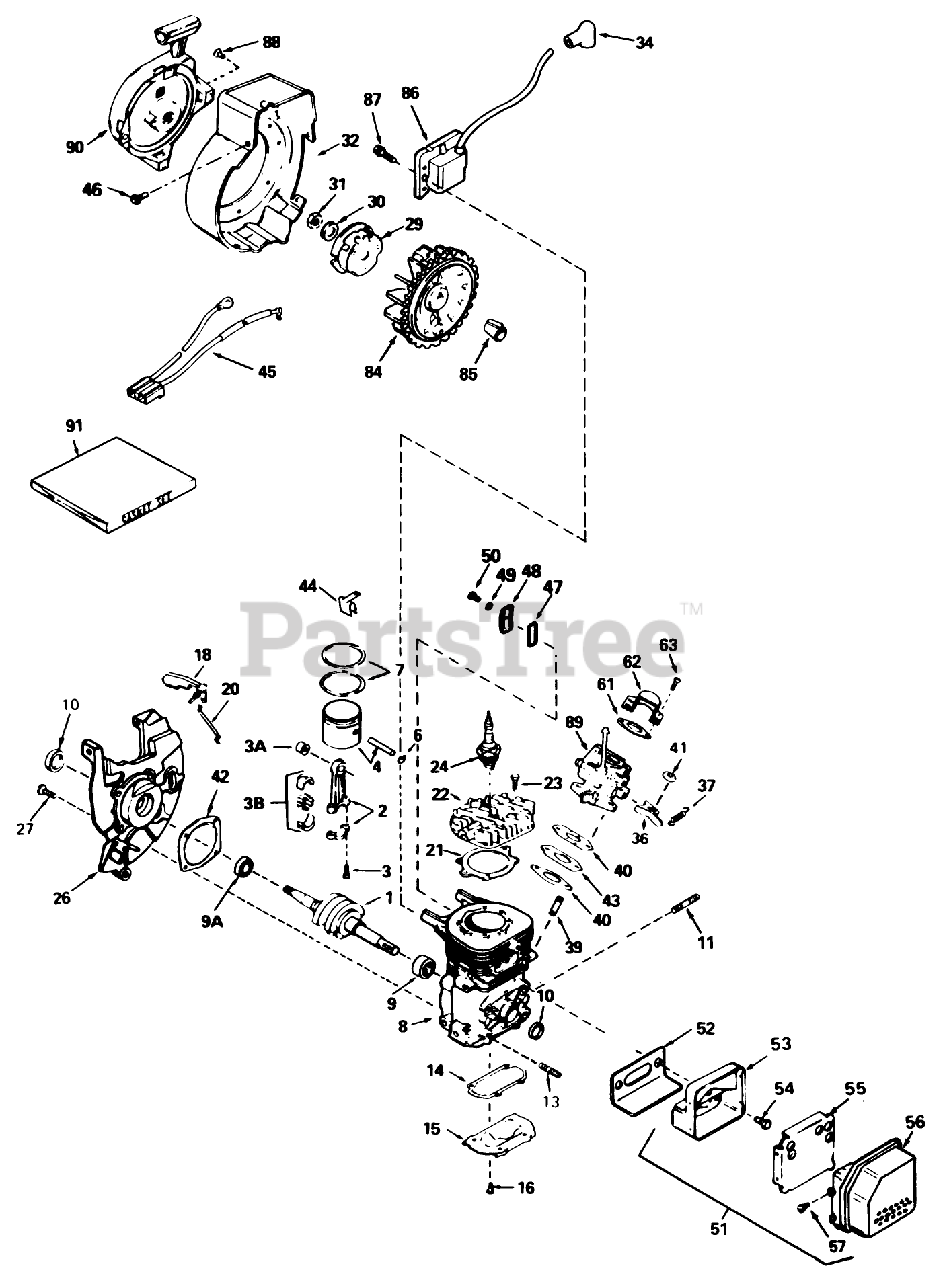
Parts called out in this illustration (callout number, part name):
1	Crankshaft
2	Rod Assy.-Connecting (Incl. Ref. #3, 3A 3B)
3	Bolt-Rod, Connecting
3A	Bearing-Cartridge
3B	Needle Bearing and Liner Set (37 Needles)
4	Piston (Incl. Ref. #43)
6	Ring-Retaning
7	Ring Set
8	Cylinder Block Assembly
9	Bearing-Cartridge
9A	Bearing-Ball
10	Seal-Oil
14	Cover
15	Plate-Cover
16	Screw (T-25, 10-24 x 1/2)
18	Vane-Air
20	Link-Governor
21	Gasket-Head, Cylinder
22	Head-Cylinder
23	Screw (T-30, 1/4-20 x 3/4)
24	Spark Plug-Resistor (R C J 8Y)
26	Blower Housing Base Assy. (Incl. Ref. #10)
27	Screw (T-30, 1/4-20 x 5/8)
29	Cup-Starter
30	Washer-Belleville
31	Nut-Flywheel
32	Housing-Blower
34	Cover-Spark Plug
36	Lever-Adjusting, Rpm
37	Spring-Governor
40	Gasket-Carburetor
41	Locknut
42	Gasket-Cover, Cylinder
43	Spacer
44	Clip-Wire
45	Harness-Wire
46	Screw-Hex, Hd.
47	Cover-Compression, Release
48	Comp. Release Cover
49	Washer
50	Screw (T-25, 10-24 x 1/2)
51	Muffler Assembly (Incl. Ref. #53-57)
52	Gasket-Exhaust
53	Base-Muffler
54	Screw (T-30, 1/4-20 x 5/8)
55	Baffle-Muffler
56	Cover Muffler
57	Screw
61	Gasket
62	Baffle-Carburetor
63	Screw
84	Flywheel
85	Blade (20 inch)
86	Solid State
87	Screw
88	Rivet-Pop
89	Carburetor (Incl. Ref. #184A)
90	Starter-Rewind
91	Gasket Set
